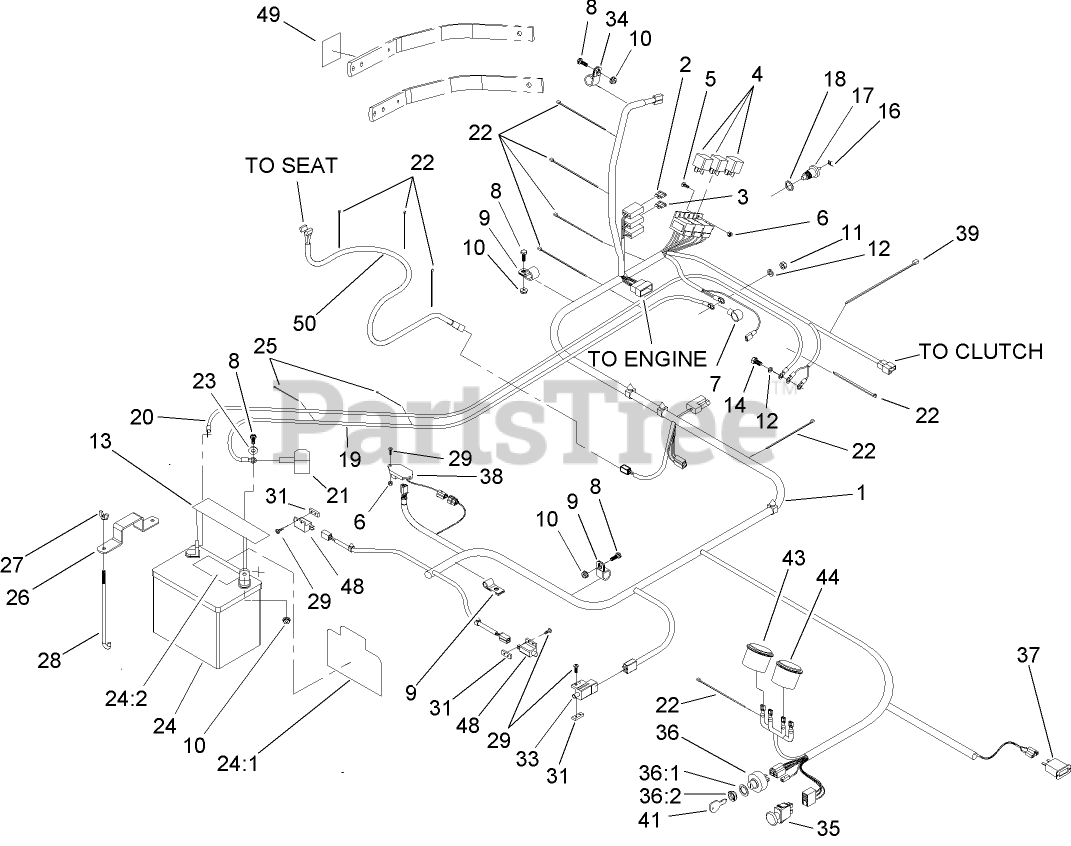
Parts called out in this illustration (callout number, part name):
1	Harness-Wire
2	FUSE-BLADE TYPE, 20 AMP
3	FUSE-BLADE TYPE, 30 AMP
6	NUT-LOCK, NI
7	INSULATOR-SOLENOID
8	SCREW-HH
9	CLIP-LOOM
10	NUT-HF
11	NUT-HEX
12	WASHER-PLAIN
13	Decal-Warning, Battery
14	SCREW-HH
17	SENDER-TEMPERATURE
18	WASHER-ALUMINUM
19	WIRE-BATTERY, POSITIVE
20	WIRE-GROUND
21	INSULATOR-BATTERY
22	TIE-PLASTIC
23	WASHER-FLAT
24	BATTERY
24:1	Decal-Battery
24:2	Decal-Battery
25	TIE-CABLE
26	STRAP-HOLDDOWN
27	WINGNUT
28	BOLT-HOLDDOWN
29	SCREW-PPH
31	PLATE-TAPPED
33	SWITCH
34	CLIP-LOOM
35	SWITCH-DELTA
36	Key Switch ASM
36:1	WASHER-TOOTH, INTERNAL
36:2	NUT-HH
37	METER-HOUR
38	MODULE-DELAY, SEAT
39	TIE-PLASTIC
41	KEY-IGNITION
43	GAUGE-VOLTMETER
44	GAUGE-TEMPERATURE
48	SWITCH-OPEN, NORMALLY
49	Decal-Relay
50	HARNESS-WIRING, SEAT
